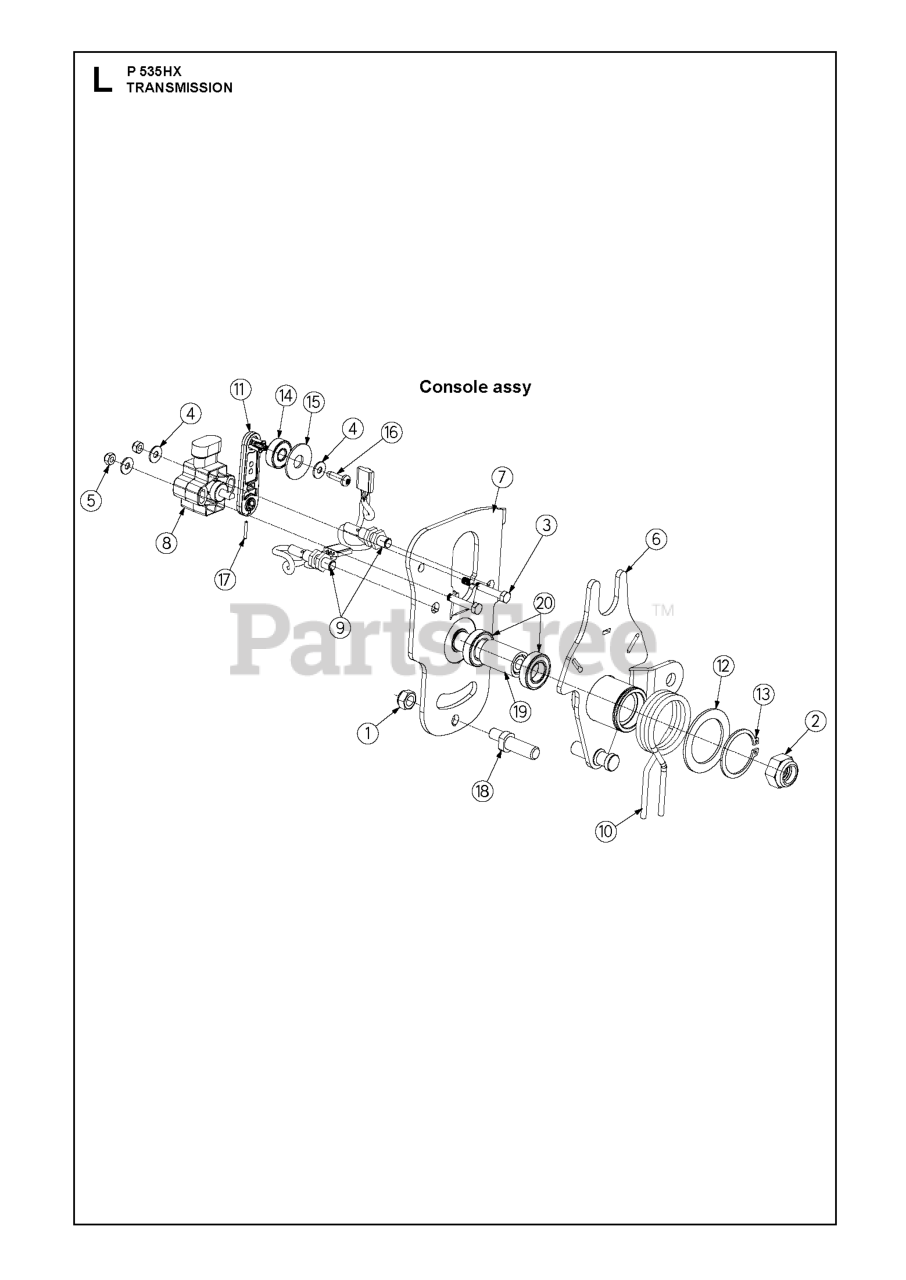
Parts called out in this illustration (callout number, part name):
1	LOCKNUT M8
3	SCREW M6S 5X40
5	LOCKNUT M5
14	BALL BEARING
